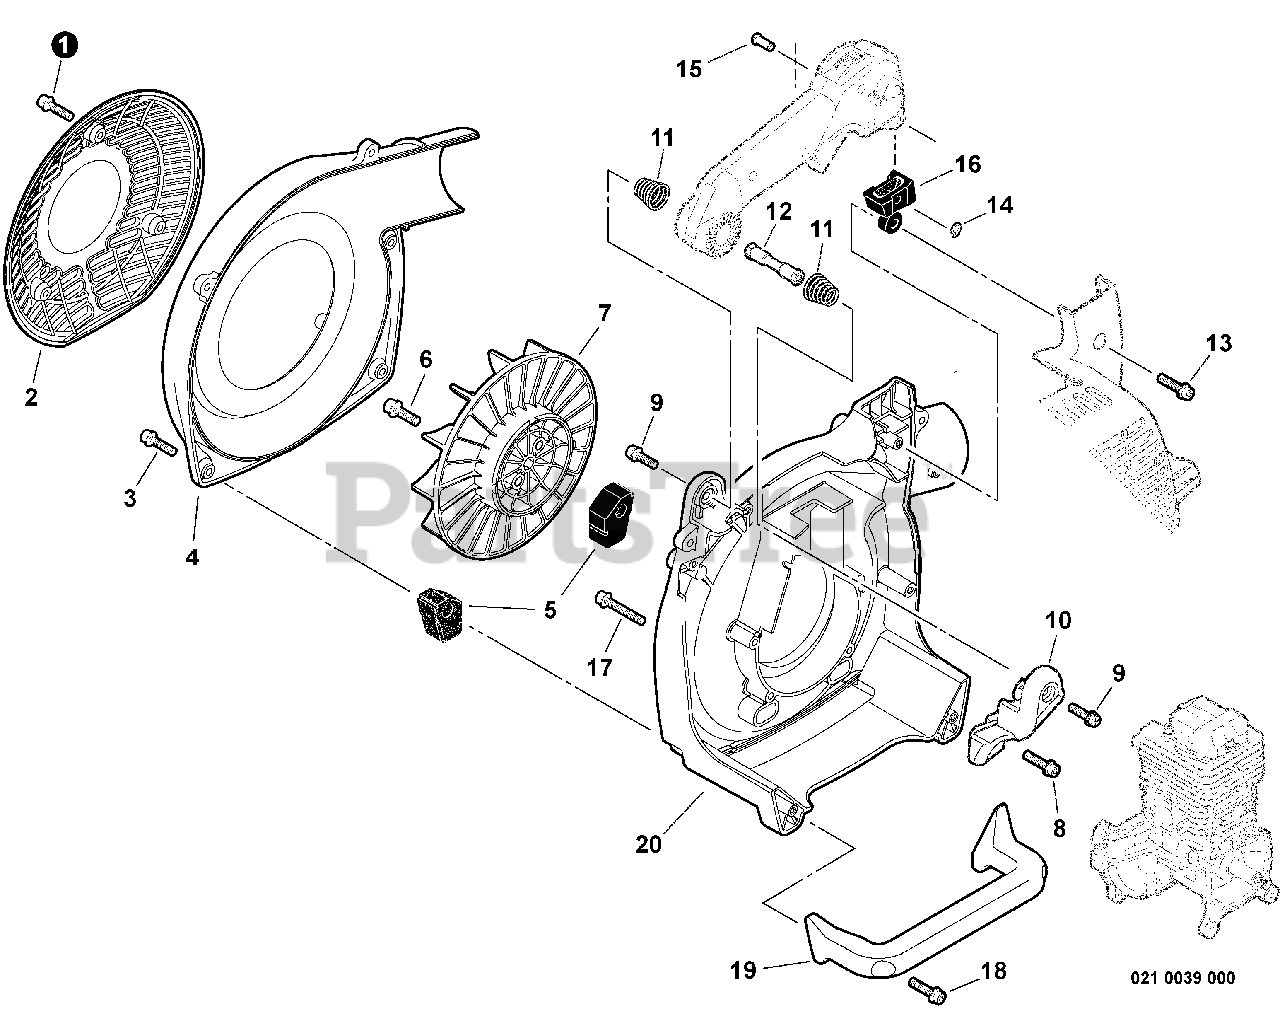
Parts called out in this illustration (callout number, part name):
1	SCREW - 5X20
2	GUARD, DEBRIS
3	SCREW - 5X20
4	COVER, FAN - LEFT
5	CUSHION
6	BOLT - 6X20
8	SCREW - 5X20
9	SCREW - 5X16
10	MOUNT, HANDLE
13	SCREW - 5X20
14	RING, RETAINING - 8
15	PIN - LOCKING
16	CUSHION
17	SCREW - 5X40
18	SCREW - 5X20
19	HANDLE - SIDE
20	COVER, FAN - INNER
